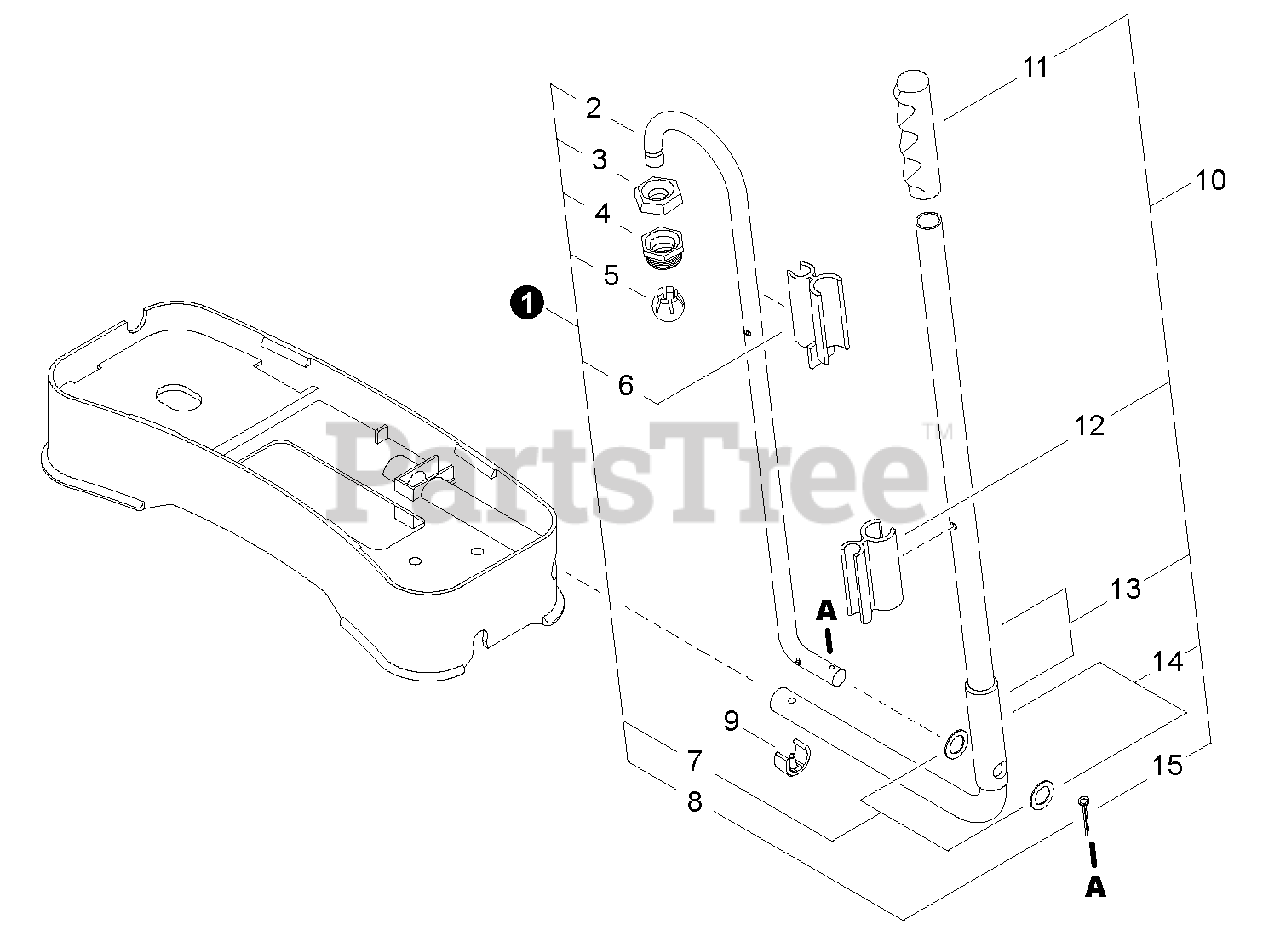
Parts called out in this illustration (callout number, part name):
1	PUMP ARM KIT
2	ARM, PUMP
3	BOOT, JOINT
4	NUT, JOINT
5	JOINT, BALL
6	CLIP, PUMP LEVER
7	WASHER
8	PIN, SPLIT
10	PUMP LEVER KIT
11	GRIP, LEVER
12	CLIP, WAND
13	LEVER, PUMP
14	WASHER
15	PIN, SPLIT
